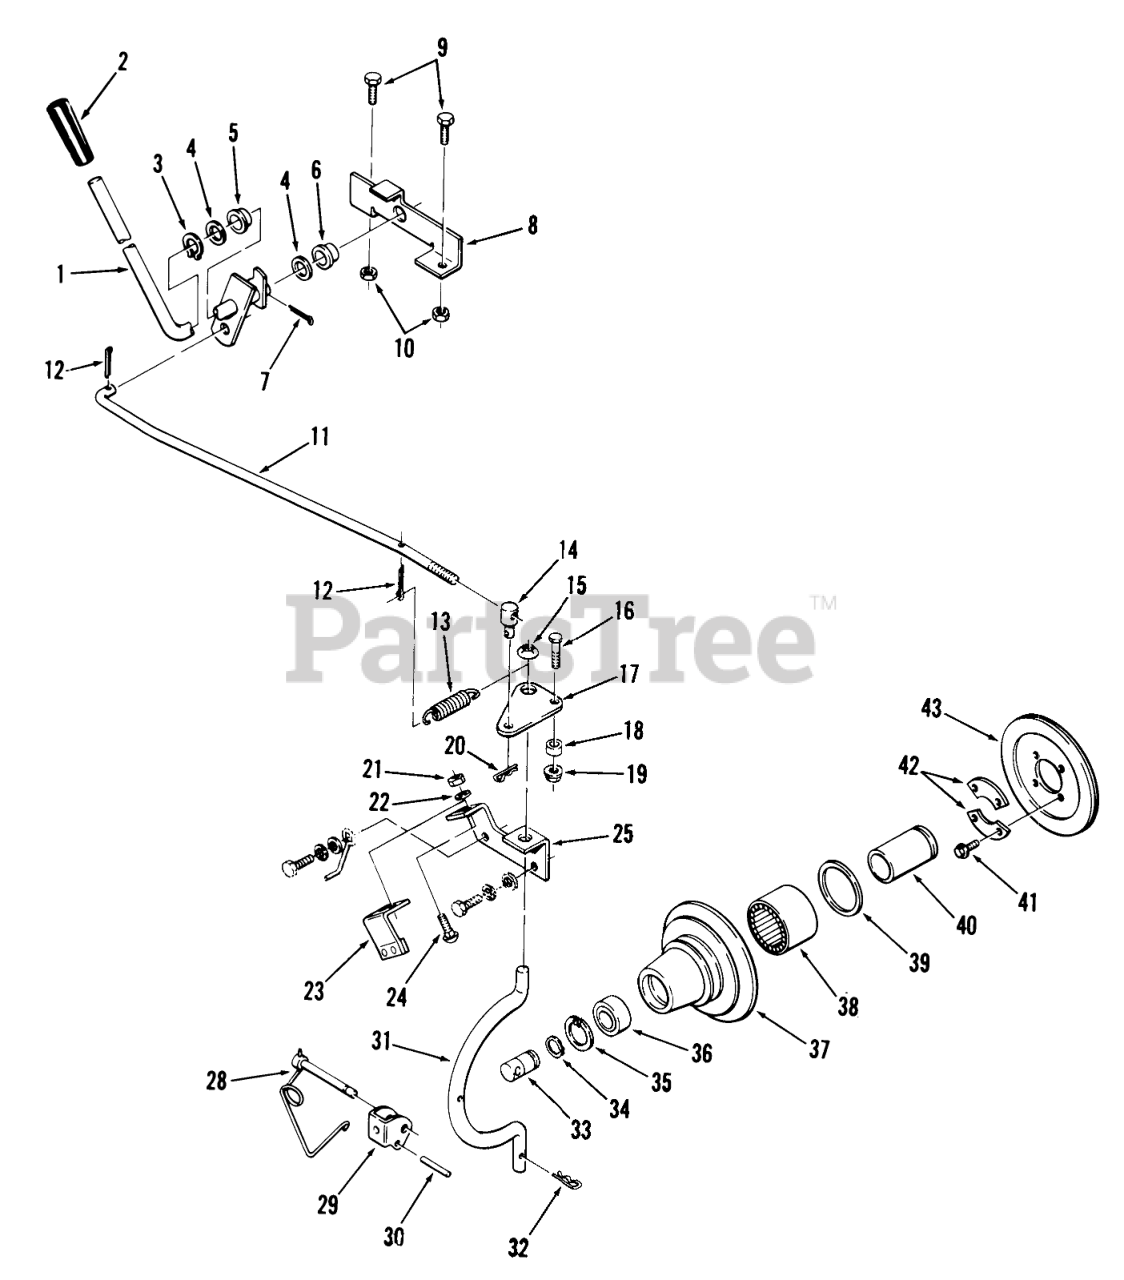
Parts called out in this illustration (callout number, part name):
1	PTO Clutch Lever
2	GRIP
3	Grip Ring
4	SHIM-WASHER
5	BUSHING-NYLINER
6	NYLINER BUSHING
7	Pop Rivet
8	SUPPORT-PTO CLUTCH
9	Bolt
10	Nut
11	PTO Clutch Rod
12	Pop Rivet
13	SPRING
14	TRUNNION
15	RING-REINFORCED CIRC
16	BOLT
17	PTO Plate
18	SPACER
19	LOCKNUT-FLANGE
20	Hairpin Cotter
21	Nut
23	PTO Plate
24	Bolt-Carriage
25	BRACKET
25	BRACKET-ENGINE B
26	LOCKWASHER
27	7/16-14 x 1 1/4 Bolt
28	Pin
29	Clevis
30	PIN-SPIROL
31	ROD-HOUSING
31	PTO Housing Rod C-175 Twin Only
32	Hairpin
33	SHAFT-PTO
34	RING-SNAP, EXTERNAL
35	Ring-Snap
36	BaIl Bearing
37	Housing-Clutch
38	BRG-NEEDLE OPEN END
39	SEAL-OIL
40	RACE-BEARING
40	BEARING RACE
41	Screw
42	RETAINER
43	Clutch Plate & Facing
44	WASHER
